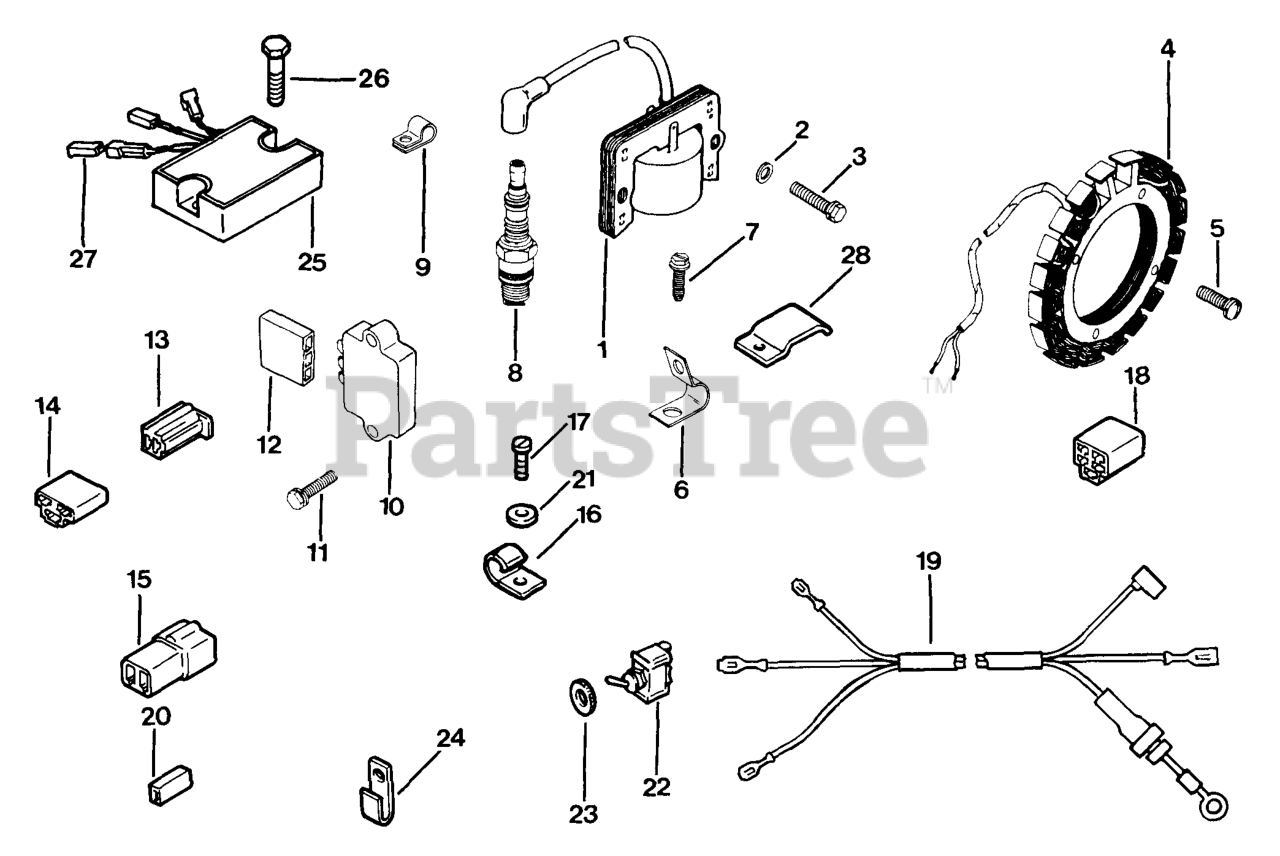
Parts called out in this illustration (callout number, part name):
1	MODULE - USE 47 584 02
2	WASHER, FLAT 3/16"
3	SCREW - USE X-67-51-S
4	KIT, 15 / 20 AMP STATOR
5	SCREW, WSH HD TAP #10-24X3/4" USE 25 086 97-S
7	SCREW, WASHER HD TAP #8-32X3/8" USE 25 086 99-S
8	SPARK PLUG USE 25 132 10-S
10	KIT - USE 25 755 03
10	KIT, REGULATOR/RECTIFIER
11	SCREW
11	SCREW, SEMS 1/4-20X5/8" USE 25 086 539-S
12	CONNECTOR, BODY (KM)-USE 25 155 41-S
